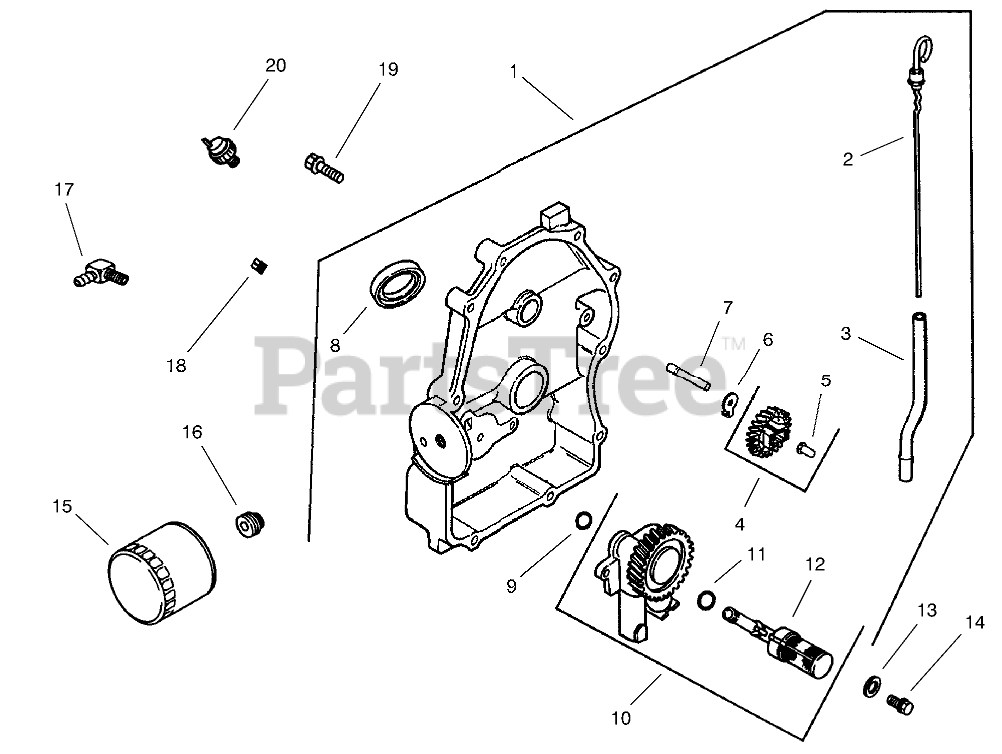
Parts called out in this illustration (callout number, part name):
1	Plate, closure assembly (Includes 2-12)
2	Dipstick
3	Tube-Dipstick
4	Kit, governor gear (Includes 5)
5	Pin-Governor
6	Tab-Locking
7	Shaft-Gear, Governor
8	Seal-Oil
9	O Ring
10	Oil pump assembly (Includes 11,12)
11	O-Ring
12	Pick Up-Oil
13	Washer
14	Screw
15	Filter-Oil
16	Nipple-Filter, Oil
17	Connector
18	Plug
19	Screw
20	Switch, pressure
